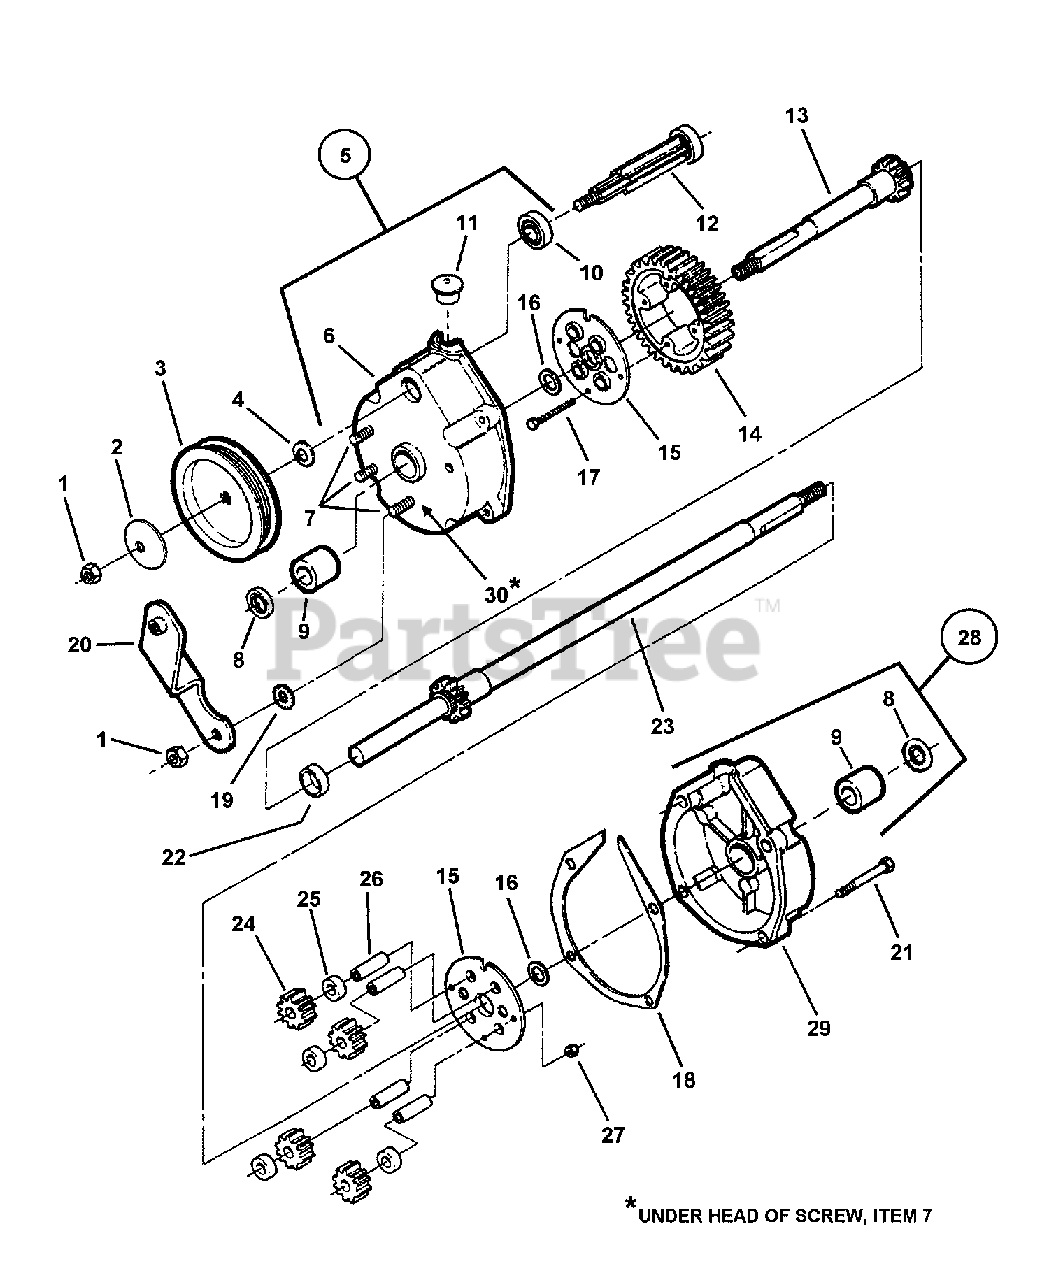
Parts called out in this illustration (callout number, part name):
1	NUT, 5/16-18 Hex Lock
2	WASHER, Cone
3	PULLEY, Poly-V Belt (3.5 O.D.)
4	WASHER, Spring
5	ASSEMBLY, Right Housing (Incl. items 6, 7, 8, 9, 10 & 30)
6	HOUSING, Right Side
7	SCREW, 5/16-24 x 1-1/8" Rib Neck, GR 5
8	SEAL, 5/8" Internal Diameter
9	BEARING, Tapered- (Differential Housing)
10	BALL BEARING, 7/16 I.D., 1/1/8" O.D.
11	PLUG, Transmission Housing
12	GEAR, Input
13	ASSEMBLY, Short Axle
14	** GEAR, Differential (46 Tooth)
15	PLATE, 46T Gear
16	WASHER, Thrust, 3/4" I.D.
17	SCREW, #10-32 x 1-1/2" Hex Head Cap GR5
18	GASKET, Housing
19	WASHER, 5/16" Internal/External Tooth Lock
20	WELDMENT, Differential Bracket
21	SCREW, 1/4-20 x 1" Hex Washer Self-Tap
22	SPACER, Axle Gear
23	ASSEMBLY, Long Axle
24	GEAR, Pinion (12 tooth)
25	SPACER, Pinion Gear
26	SHAFT, Pinion
27	NUT, #10-32 Hex Nyloc
28	ASSY, Left Housing
29	HOUSING, Left
30	GASKET, 5/8" O. D.
